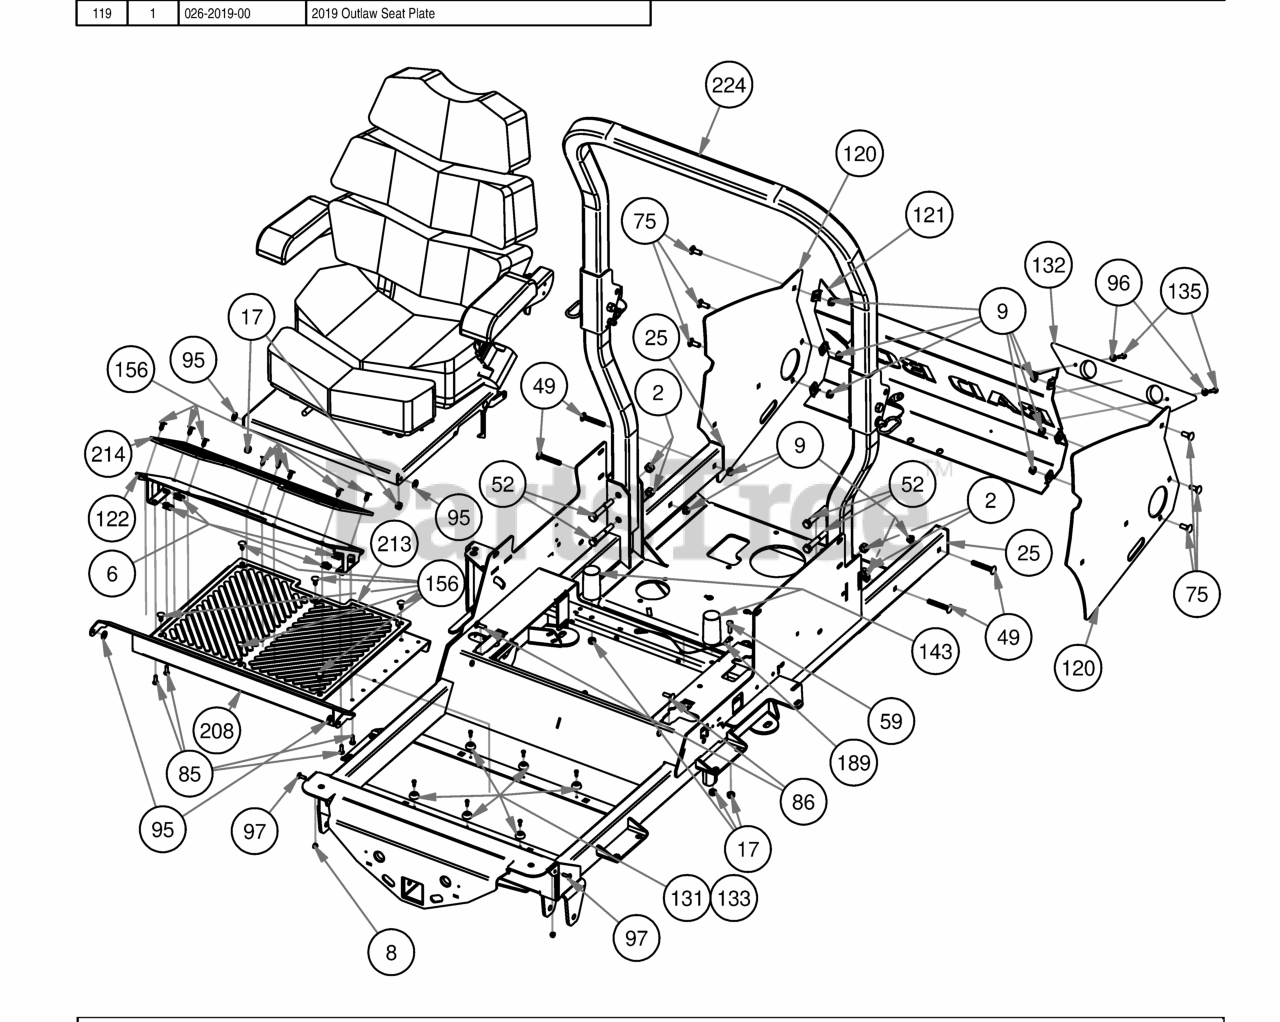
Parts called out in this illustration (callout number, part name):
2	1/2" Center Lock Nut
6	1/4-20 Cage Nut
8	1/4-20 Hex flang lock nut
9	3/8" Nylock Flange Nut
17	5/16-18 Nylon Flange Nut
25	1 1/2 x 3 Frame Plug
49	3/8" x 2 1/2" Carriage Bolt
52	1/2-13 X 3.25 Hex Bolt - Grade 5
59	5/16" x 1" Bolt
75	3/8" x 1" Carriage Bolt
85	1/4" x 3/4" Hex Bolt
86	5/16" x 1" Carriage Bolt
95	.360 ID Plastic Washer
96	1/4" Flat Washer
97	1/4" x 3/4" Carriage Bolt
120	2019 Rouge Rear Cover Side Plate
121	2019 Vertical Rear Cover Tailgate Plate
122	2019 Outlaw Adjustable Foot Plate
131	Button Bumper
132	2017 XP Bumper
133	#10 x 1/2" Self Tapping Screw
135	1/4 x 1 Hex Head Tek screw
143	2019 Bad Boy X Cylindrical Seat Mount
156	Ratchet Fastener
189	Seat Cable
203	2019 Veritical Suspension Frame
208	2019 Outlaw Floorboard
213	OUTLAW2019_FLOORMAT
214	FLOORMAT_OUTLAW_2019
224	2019 2X2 Folding ROPS
